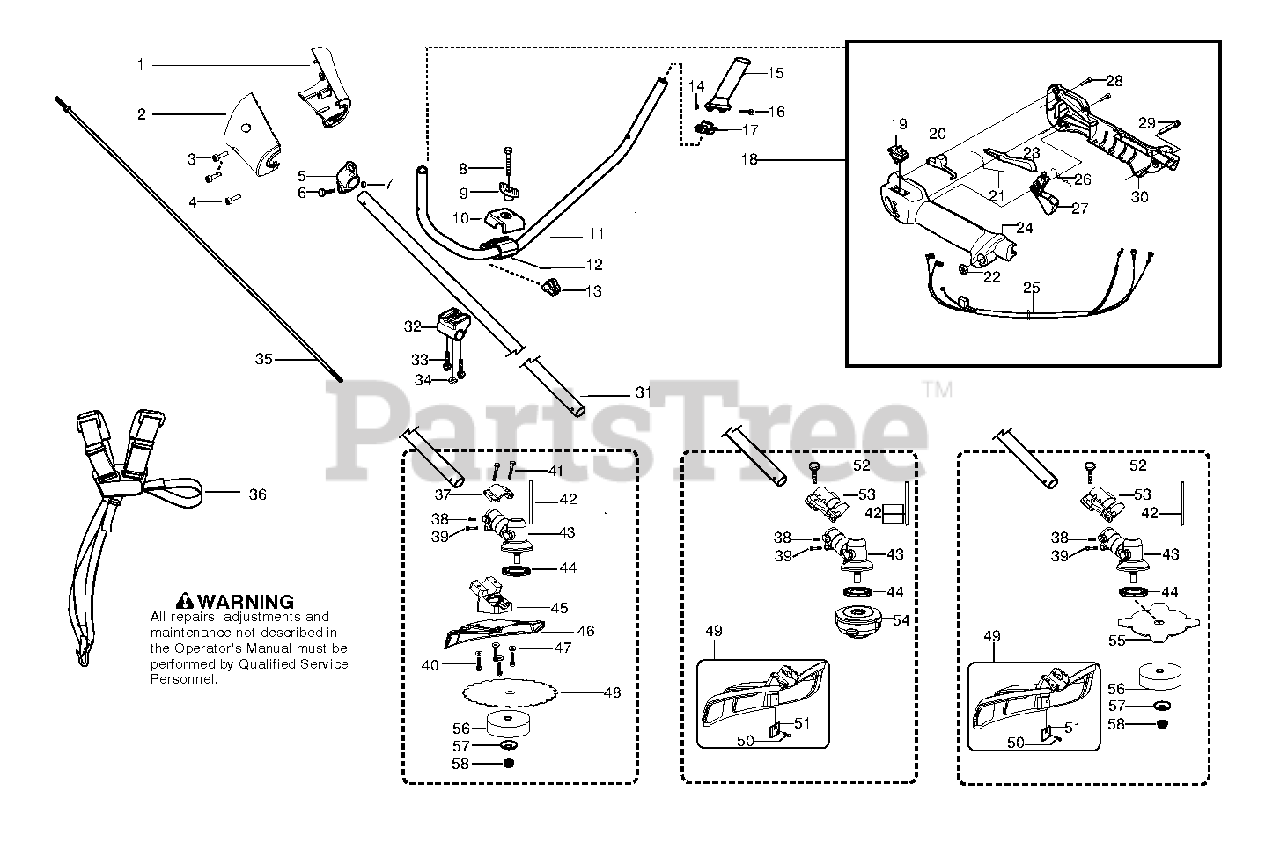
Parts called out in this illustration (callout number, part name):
4	SCREW M4 X 1.75 PT 16MM
12	HOLDER
19	STOP BUTTON
23	TRIGGER SAFETY
25	ASSY CABLE WIRE HARNESS
27	TRIGGER
29	%SCREW
41	BOLT FLANGE - M6X20
42	LOCKING PIN
44	DRIVE DISC
46	METAL GUARD 200MM
47	WASHER 5.3X12
51	LINE CUTTER
53	RP BRACKET TRIMMER GUARD
54	T25 TRIM HEAD 10MM LH
55	BLADE GRASS
56	SUPPORTING CUP
57	SUPPORT FLANGE
58	GEARHEAD NUT - BRUSHCUTTER
